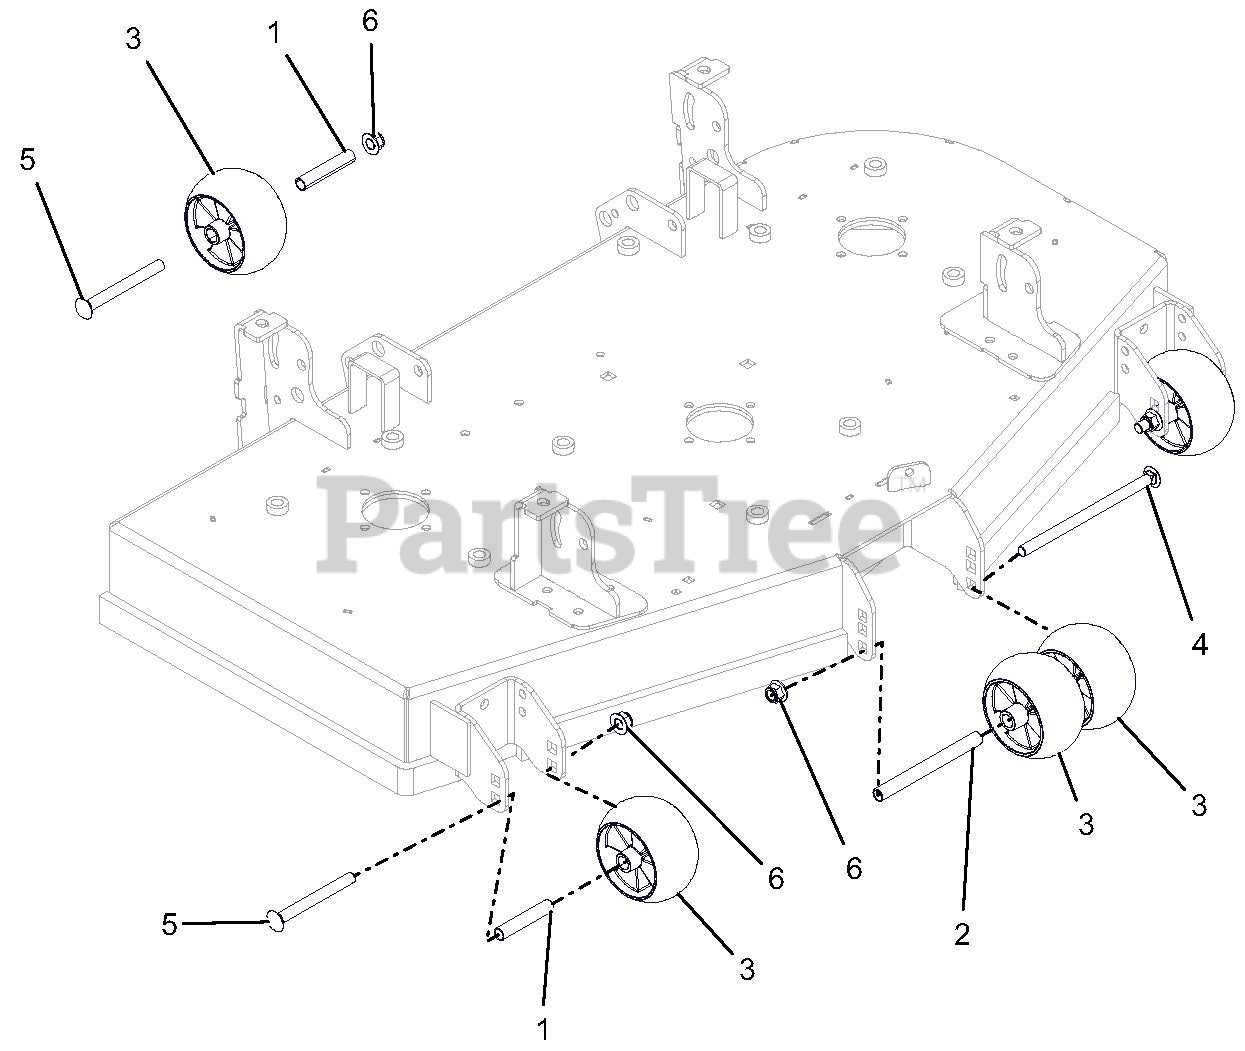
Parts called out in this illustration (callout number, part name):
1	SPACER, .510X.625X3.35
2	SPACER, .510 X .625 X 6.50
3	ANTI-SCALP WHEEL - 5X3 CTR
4	BLT-RDHDSQNK .50-13X8.50 Y
5	BLT-RDHDSQNK .50-13X5.00 G5 YWZC
6	NUT-LK-NYL-FLG .50-13 YWZC
